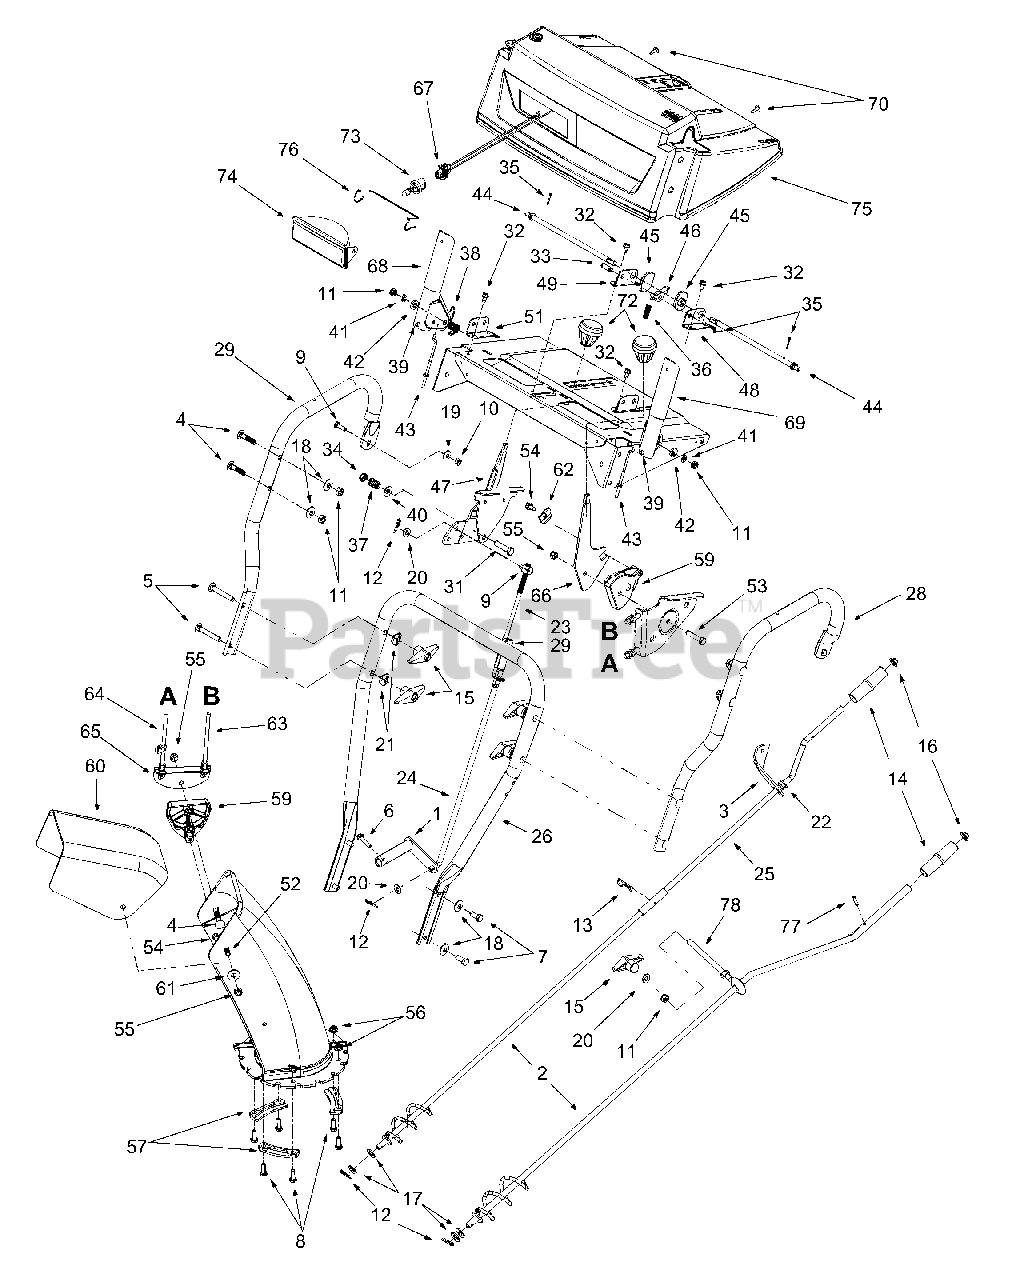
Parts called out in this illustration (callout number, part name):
4	Carriage Bolt, 5/16-18 x 1.5
5	Carriage Bolt, 5/16-18 x 2.25
6	Self Tapping Screw, 1/4-20 x 1
7	Hex Cap Screw, 5/16-18 x .75
8	Hex Cap Screw, 1/4-20 x .75
9	Ferrule, 5/16-18 x .312
10	Hex Nut, 1/4-20
11	Hex Nut, 5/16-18
12	Internal Cotter Pin
13	Click Pin
14	Chute Crank Knob
15	Wing Knob, 5/16-18
16	Push Cap, 3/8
17	Flat Washer, .375 x .738 x .063
18	Bell Washer, .34 x .872
19	Bell Washer, .265 x .75 x .062
20	Flat Washer, .344 x .688 x .065
21	Saddle Washer, .32 x .93
22	Plastic Bushing
23	Upper Shift Rod
24	Lower Shift Rod
31	Hex Cap Screw, 3/8-24 x 1.5
32	Self Tapping Screw, 1/4-20 x .5
33	Clevis Pin
34	Jam nut, 3/8-24
35	Cotter Pin, 3/32 x .75
36	Compression Spring, .36 x 1.0
37	Comp. Spring, .39 x .6 x .88
38	Torsion Spring, .44 x .8
39	Rubber Bumper
40	Bell Washer, .401 x .87 x .063
41	Lock Washer, 5/16
42	Special Washer, .35 x .72 x .13
43	"Z" Fittings For Control Cables
44	Cam Rod
45	Cam Handle Lock
46	Handle Lock Pawl
52	Carriage Bolt, 5/16-18 x .75
53	Hex Cap Screw, 516-18 x 1.5
54	Screw, 1/4-14 x .625
55	Hex Lock Nut, 5/16-18
56	Hex Flange Lock Nut, 1/4-20
57	Lower Chute Flange Keeper
59	Chute Tilt Cable Guide
60	Upper Chute
61	Washer, 5/16
62	Special Washer, .28 x 1.2 x .06
63	Chute Deflector Control Cable
64	Chute Deflector Cable w/ Clip
67	Halogen Light Harness
68	RH Engagement Handle Ass'y
69	LH Engagement Handle Ass'y
70	Special Screw, #10-16 x .625
72	Plastic Knob
73	Halogen Lamp, 12-volt, 27 Watt
74	Lens Assembly / Lamp Housing
75	Handle Panel, Yellow
76	Headlamp Retainer
77	Rolled Pin
78	Eyebolt
